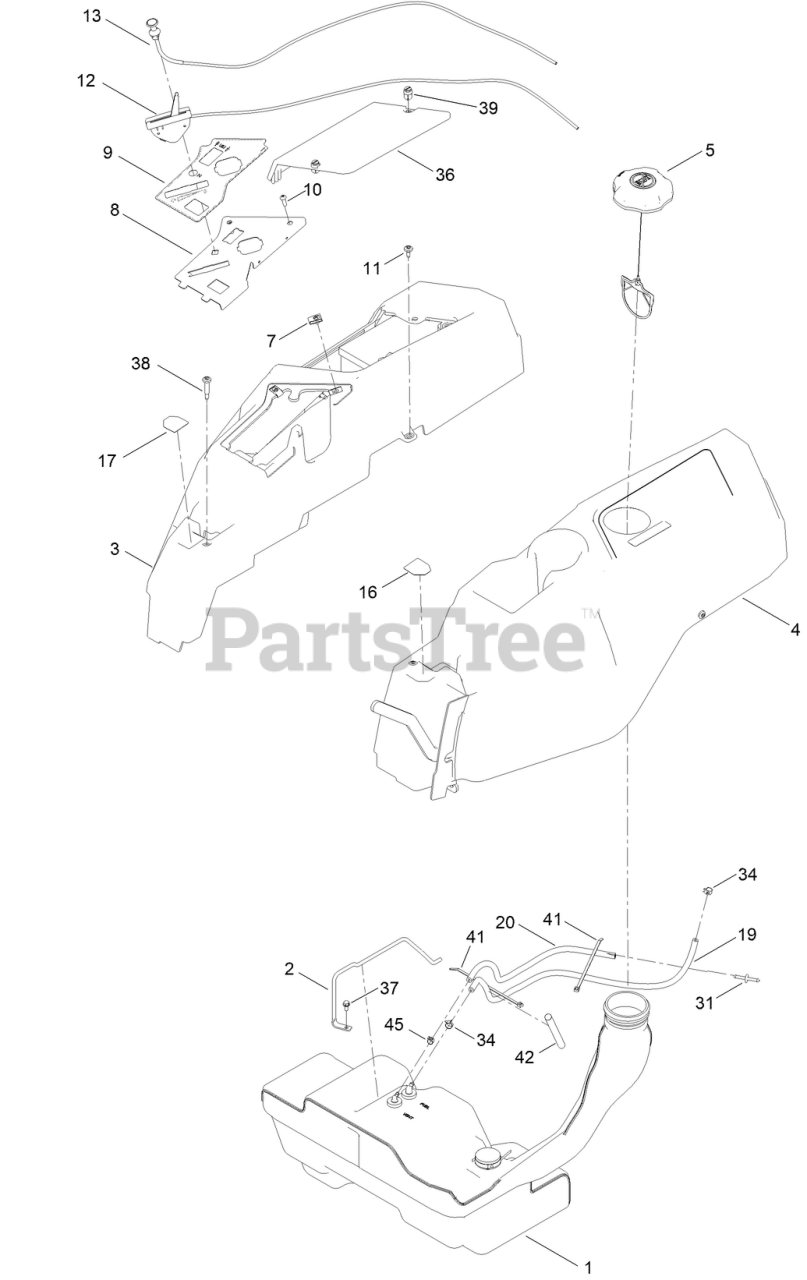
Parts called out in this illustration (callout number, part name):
1	TANK-FUEL ASM
2	ROD-HOLD DOWN
3	POD-RH
4	POD-LH
5	CAP-FUEL, RATCHETING
8	PANEL-CONTROL
9	DECAL-PANEL, CONTROL
10	SCREW-PRH
11	SCREW-SHOULDER
12	CABLE-THROTTLE
13	CABLE-CHOKE
16	DECAL-LEVER, CONTROL (LH)
17	DECAL-LEVER, CONTROL (RH)
19	HOSE-FUEL
20	HOSE-VENT
31	ADAPTER ORIFICE
34	CLAMP-HOSE
36	COVER-BATTERY
37	SCREW-HWH
38	SCREW-SHOULDER
39	FASTENER
41	TIE-CABLE
42	SLEEVE-FUEL LINE PROTECTOR
45	CLAMP-HOSE
